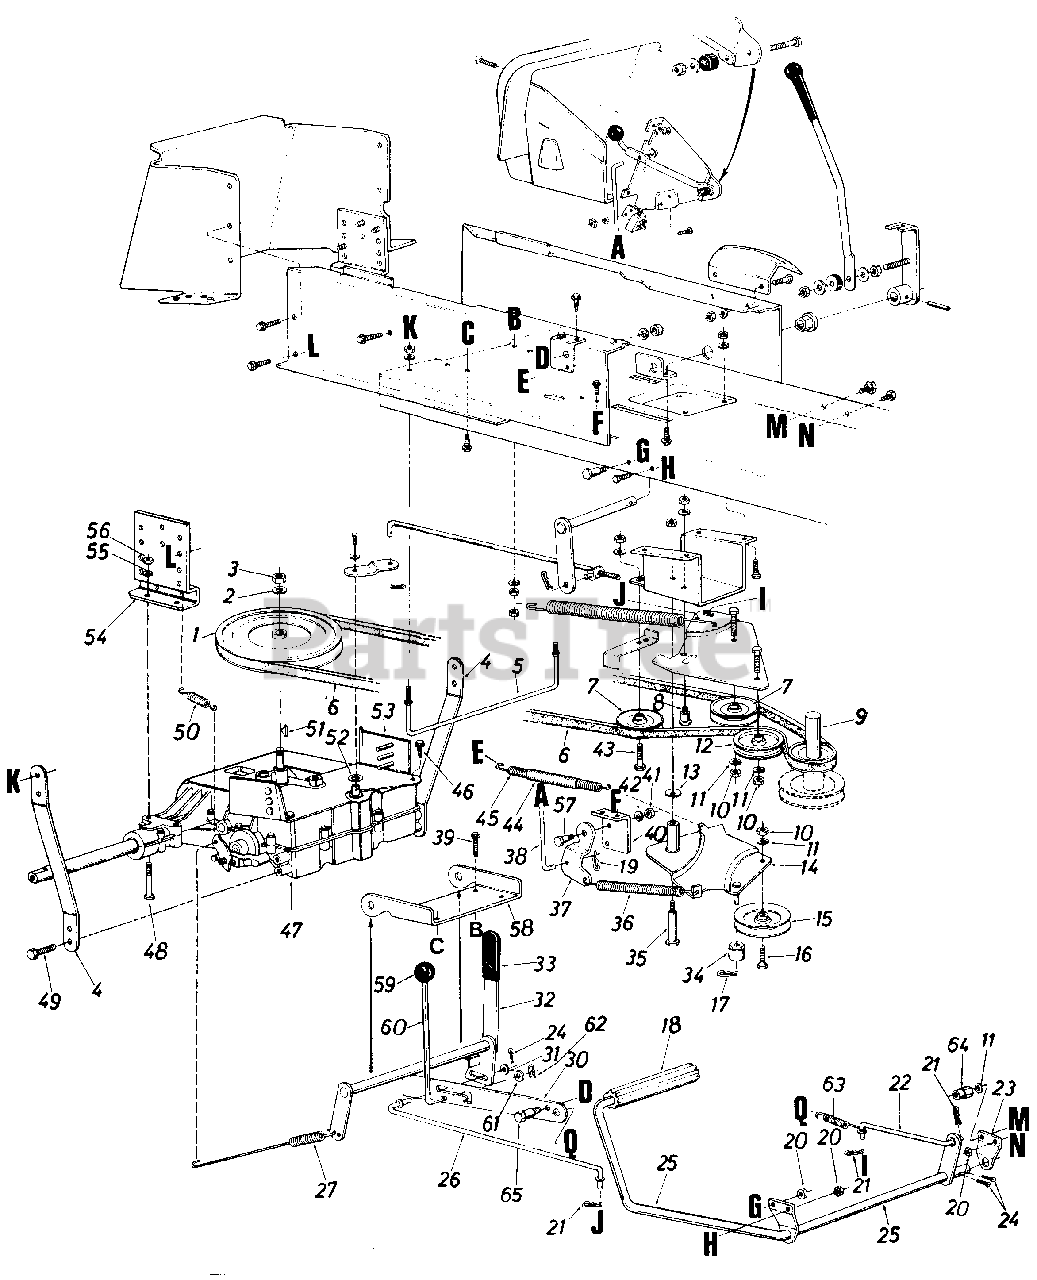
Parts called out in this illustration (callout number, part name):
1	8" "V"-Pulley
2	L-Wash. 1/2" I.D.
3	Hex Nut 1/2-20 Thd.
4	Transaxle Brace
6	"V"-Belt
7	"V"-Belt Idler Pulley .38n l.D. x 3-1/16" O.D.
8	Shoulder Bolt .435" Dia. x 160 (5/16-18)
9	Two Step Engine Pulley 3.10" & 5.56" Dia.
10	Hex Nut 3/8-16 Thd.
11	L-Wash. 3/8" I.D.
12	Flat Idler Pulley 2.75" O.D.
13	Belleville Wash. .400" I.D. x .88" O.D. x .063
14	Idler Bracket Ass'y.
15	4" "V"-ldler Pulley
16	Hex Bolt 3/8-16 x 1.25" Lg.
17	Hairpin Cotter 5/16" Dia.
18	Foot Pad
19	Intern. Cotter Pin 5/16" Dia.
20	Hex Cent. L-Nut 3/8-16 Thd.
21	Hairpin Cotter 3/32" Dia. x 3/4 " Lg
22	Brake Clutch Rod (4.60" Lg.)
23	Clutch Rod Bearing Brkt.
24	Cotter Pin 1/8" Dia. x 1.00" Lg.
25	Clutch Brake Pedal Ass'y.
26	Brake Cam Rod (13.60" Lg.)
27	Extension Spring .59" O.D. x.93" Lg.
30	Parking Brake Cam
31	Fl-Wash. .406" I.D. x 1.00" O.D. x .030 Thk.
32	Hand Brake Lever Ass'y.
33	Grip-Flat Bar 1-1/4" Wide
34	Spacer
35	Shoulder Bolt .496" Dia. x 2.00" Lg. (3/8-16)
36	Extension Spring .75" O.D. x 6.12" Lg.
37	Deck Control Brkt.
38	Deck Control Rod
39	Hex Wash. Hd. TT-Tap Scr. 1/4-20 x 1.50" Lg.
40	Parking Brake Cam Mtg. Brkt.
41	Hex Nut 5/16-18 Thd.
42	L-Wash. 5/16" I.D.
43	Hex Bolt 3/8-24 x 1.50" Lg. (Grade 5)
44	Convoluted Conduit 50n l.D. x 4.0" Lg.
45	Ext. Spring 50n O.D. x 6.37" Lg.
46	Hex Wash. Hd. AB 0 Tap Scr. 5/16-24 x .75" Lg.
47	Transaxle
48	Hex Bolt 5/16-18 x 2.50" Lg.
49	Hex Wash. Hd. AB 0 Tap Scr. 5/16-24 x .75" Lg.
50	Extension Spring .50" O.D. x 2.75" Lg.
51	Hi-Pro Key 3/32" x 5/8" Dia.
52	Special Wash. 1.00" O.D. (Hdn.)
53	Transaxle Belt Keeper Ass'y.
54	Transaxle Support Bracket
55	L-Wash. 5/16" l.D.
56	Hex Nut 5/16-18 Thd.
57	Shoulder Bolt .437n Dia. x .162" Lg. (5/16-18)
58	Idler Mtg. Brkt.
60	Parking Brake Link
61	Fl-Wash.
62	Hairpin Cotter
63	Ext. Spring 3.12" Lg.
64	Spacer Nut 3/8-16 Thd.
65	Shld. Bolt .435n Dia. x .16"
